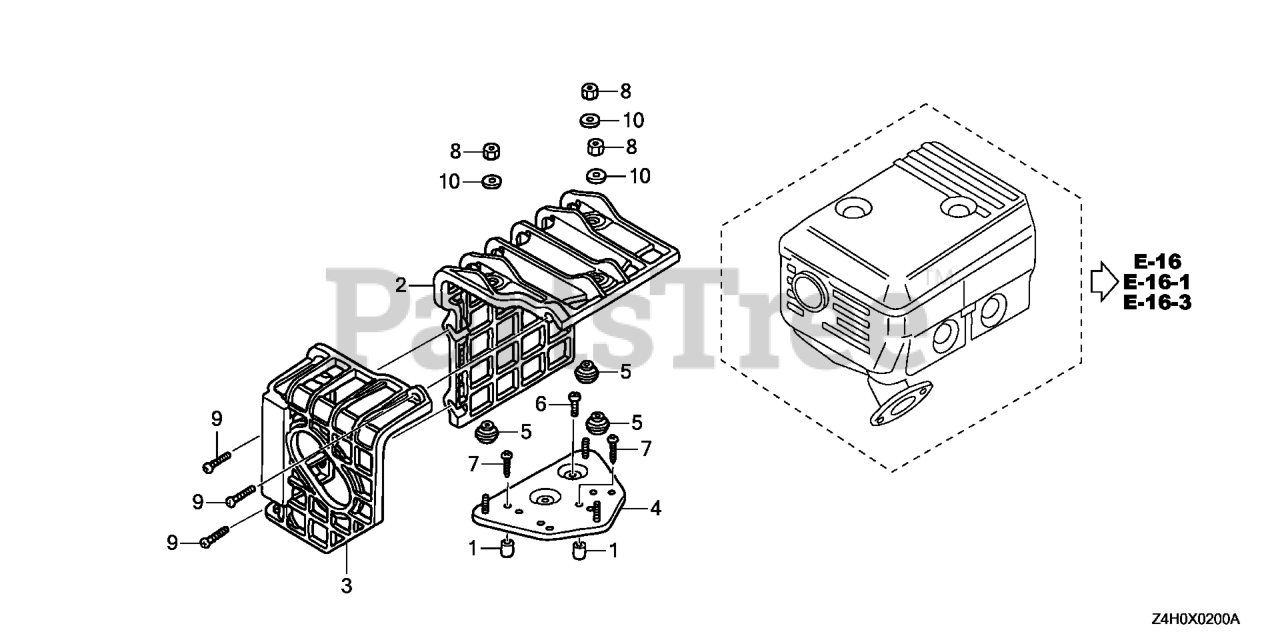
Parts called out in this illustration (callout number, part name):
1	COLLAR, AIR CLEANER HOUSING
2	COVER, MUFFLER
3	COVER, RR. MUFFLER
4	BASE, MUFFLER COVER
5	SPACER, MUFFLER COVER
6	SCREW, TAPPING (5X8)
7	SCREW, TAPPING (5X25)
8	NUT, HEX. (5MM)
9	SCREW-WASHER (6X20)
10	WASHER, PLAIN (5MM)
